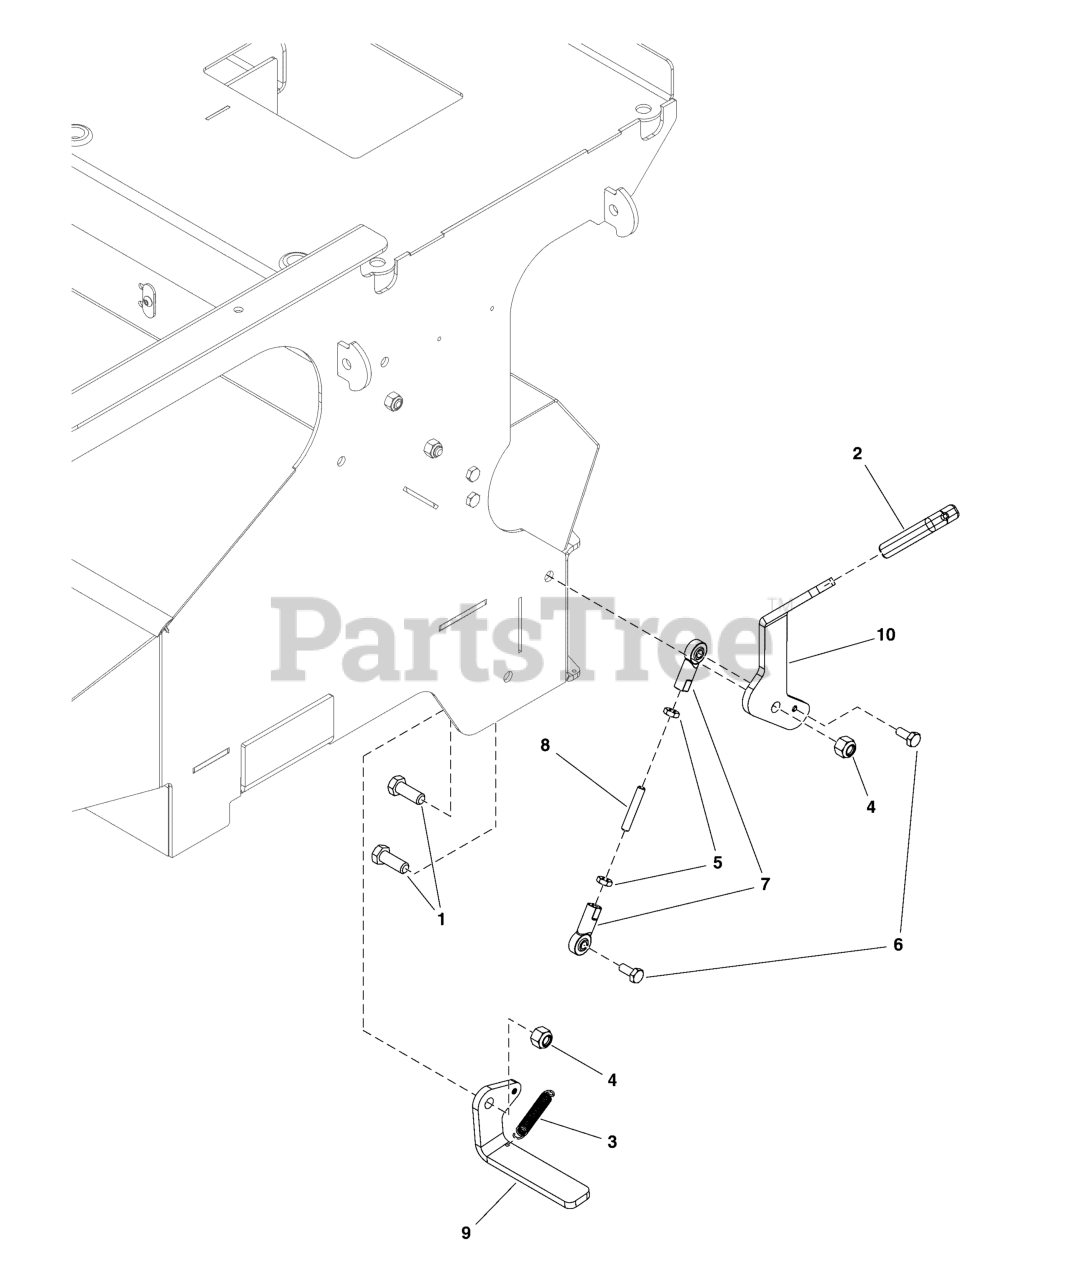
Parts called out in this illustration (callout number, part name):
1	SCR-CAP, HEX .375"-16 X 1.000" SS188
2	GRIP, .188" X 1.00" ID X .150" THK CLSD CELL FOAM
3	SPRING, EXTENSION .375" OD X 2.500 LONG SS
4	NUT-HEX-NYLK, .375"-16 SS188
5	NUT-HEX, JAM .250"-28 SS188
6	SCR-CAP, HEX .250"-20 X .625" SS188
7	ROD END, FEMALE 1/4-28 RH SS PTFE RACE
8	ROD, THREADED .250"-28 X 1.500" SS188
9	BRACKET, BRAKE BAR
10	HANDLE, PARK BRAKE
